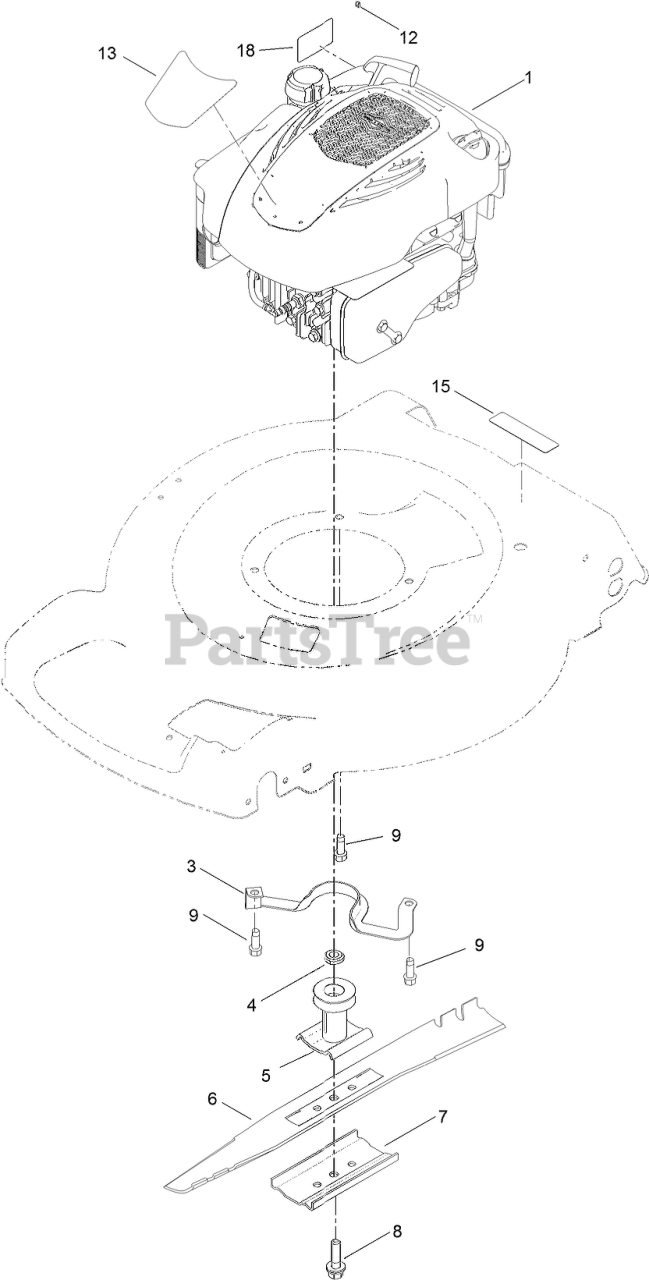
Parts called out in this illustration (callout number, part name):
3	Guide-Belt
4	Spacer-Driver
5	DRIVER-BLADE
6	BLADE-22 INCH
7	SUPPORT-BLADE
8	BOLT-BLADE
9	SCREW-TAPTITE
12	STOP-ROPE
13	DECAL-SHROUD
15	DECAL-ARRESTER, SPARK
18	DECAL-FUEL LEVEL
